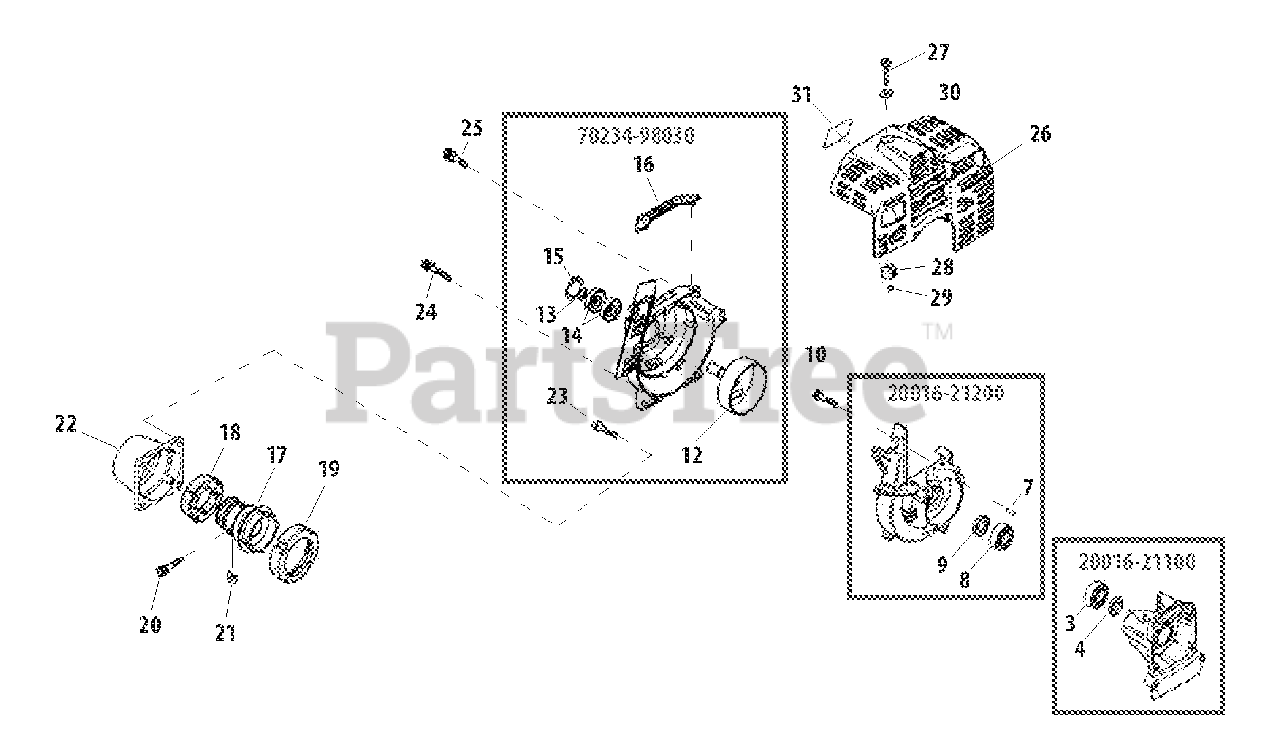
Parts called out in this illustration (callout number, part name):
3	BEARING, BALL - 6001C3
4	SEAL, OIL
7	PIN - LOCATING
8	BEARING, BALL - 6001C3
9	SEAL, OIL - 12
10	SCREW - 5X25
12	DRUM, CLUTCH
13	RING, RETAINING
14	BEARING, BALL - 6000
15	RING, RETAINING - 26
16	CUSHION
17	CLAMP, MAIN PIPE
18	CUSHION - FRONT
19	CUSHION - REAR
20	SCREW - 5X25
21	SHIM
22	CAP
23	SCREW - 5X16
24	SCREW - 5X35
25	SCREW - 5X16
26	COVER, ENGINE - RED
27	SCREW - 5X25
28	INSULATOR
29	CLIP
30	WASHER - 5
31	LABEL - MODEL
20016-21100	CRANKCASE ASSY - REAR
20016-21200	CRANKCASE ASSY - FRONT
70234-98030	FAN CASE ASSY
